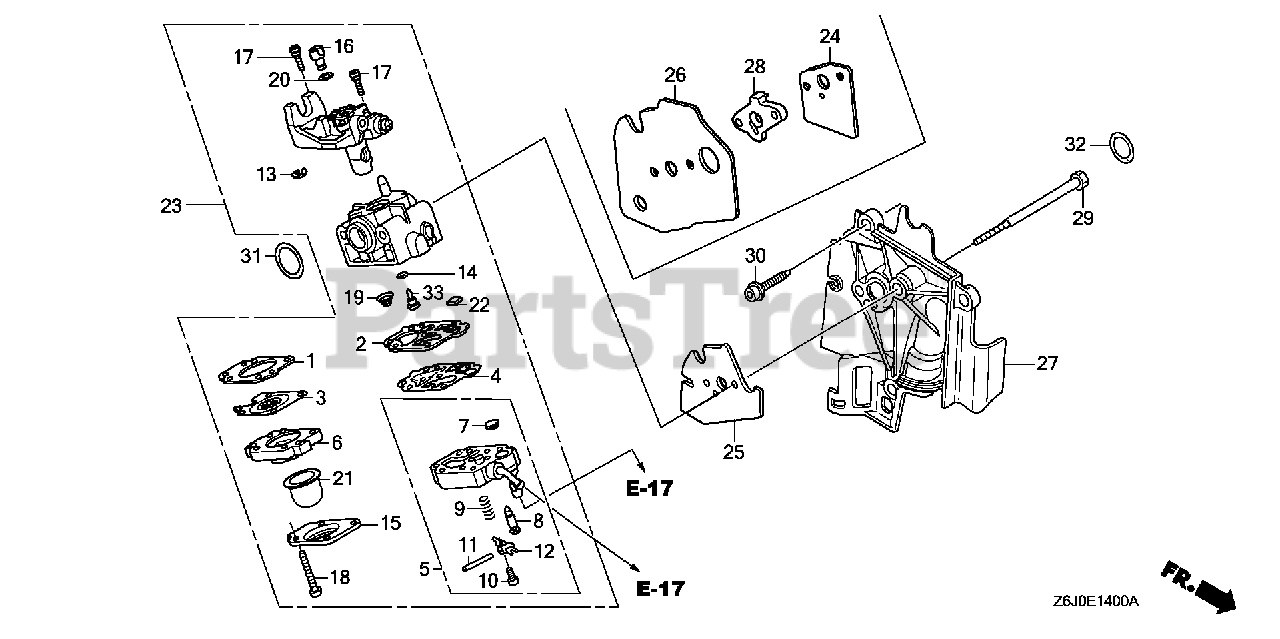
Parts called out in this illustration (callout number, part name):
1	GASKET, METERING DIAPHRAGM
2	GASKET, PUMP (CARBURETOR NO.)
3	DIAPHRAGM ASSY., METERING
4	DIAPHRAGM, PUMP
5	BODY ASSY., PUMP (CARBURETOR NO.)
6	BODY ASSY., AIR PURGE
7	SCREEN, INLET (CARBURETOR NO.)
8	VALVE, INLET NEEDLE
9	SPRING, METERING LEVER
10	SCREW, METERING LEVER PIN
11	PIN, METERING LEVER
12	LEVER, METERING
13	RING, RETAINING
15	COVER, PRIMER PUMP
17	SCREW, THROTTLE COLLAR
18	SCREW, PUMP COVER
19	SPRING, PUMP
21	PUMP, PRIMER
22	FILTER, FUEL INLET (CARBURETOR NO.)
23	CARBURETOR ASSY. (WYB 47)
24	GASKET, CARBURETOR
26	GASKET, SHROUD
28	SPACER, SHROUD
29	BOLT (5X58)
30	BOLT, SOCKET (5X16)
31	O-RING (14.8X2.4)
32	O-RING (12.3X2.4) (CARBURETOR NO.)
33	JET (#33) (CARBURETOR NO.)
33	JET (#34) (CARBURETOR NO.)
33	JET (#35) (CARBURETOR NO.)
